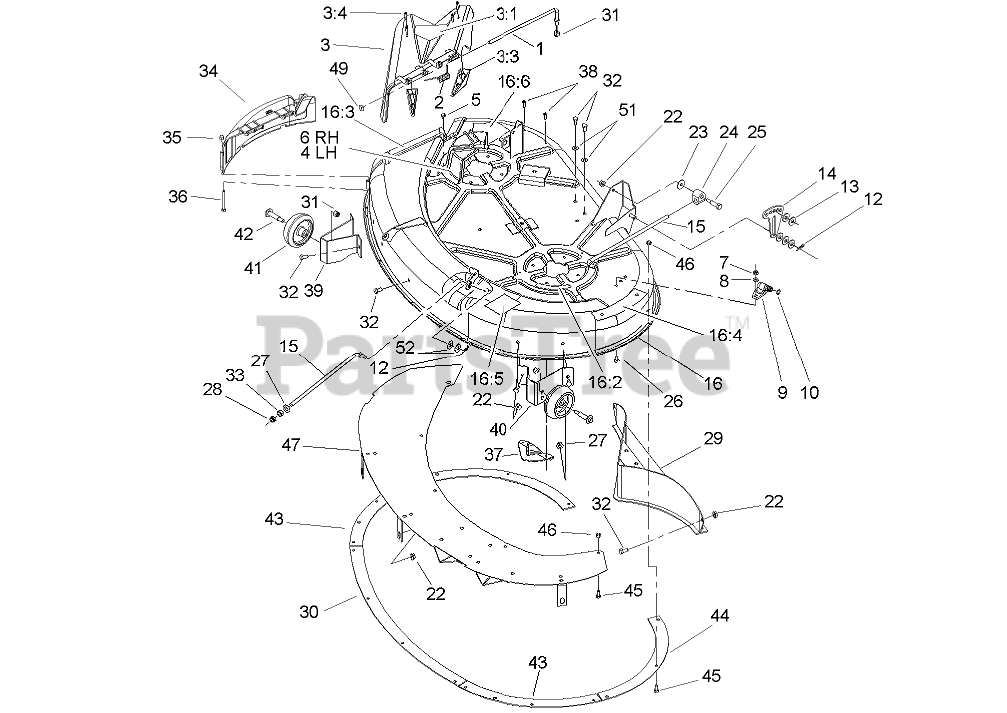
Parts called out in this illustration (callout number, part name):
1	ROD-PIVOT
2	SPRING
3	DEFLECTOR ASM
3:1	DECAL-DANGER
3:3	KICKER
3:4	SCREW-PPH
5	SCREW-HWHTF
6	GUIDE-BELT, RH
7	NUT-LOCK, NI
8	WASHER-FLAT
9	FITTING-WASHOUT
10	O-RING
12	PIN-HAIR
13	WASHER-HARDENED
14	LINK-ADJUSTING, HOC
15	ROD-HANGER
16	42in DECK ASM
16:2	DECAL-DANGER, SHIELD
16:3	DECAL-DANGER, DEFLECTOR
16:4	DECAL-DANGER
16:5	DECAL-ROUTING, BELT
16:6	DECAL-DANGER
22	NUT-HF
23	WASHER-PIVOT
24	TRUNNION-HOC
25	SCREW-SHOULDER, HH
26	BOLT-CARR
27	WASHER-FLAT
28	NUT-LOCK, NI
29	REAR BAFFLE ASM
30	RING-BLOW OUT
31	NUT-LOCK, NI
32	SCREW-HH
33	NUT-HEX
34	COVER-DISCHARGE, DECK
35	NUT-CAP
36	SCREW-HH
37	PLATE-KICKER
38	SCREW-PPH
39	BRACKET - GAGE WHEEL, FRONT RH
40	BRACKET - GAGE WHEEL, FRONT LH
41	WHEEL-GAGE
42	SCREW-SHOULDER, HWH
43	RING-BLOW OUT, SIDE
44	RING-BLOW OUT, SIDE
45	SCREW-HH
46	NUT-LOCK, NI
47	BAFFLE UPPER ASM
49	O-RING
51	WASHER-PLAIN
52	WASHER-FLAT
